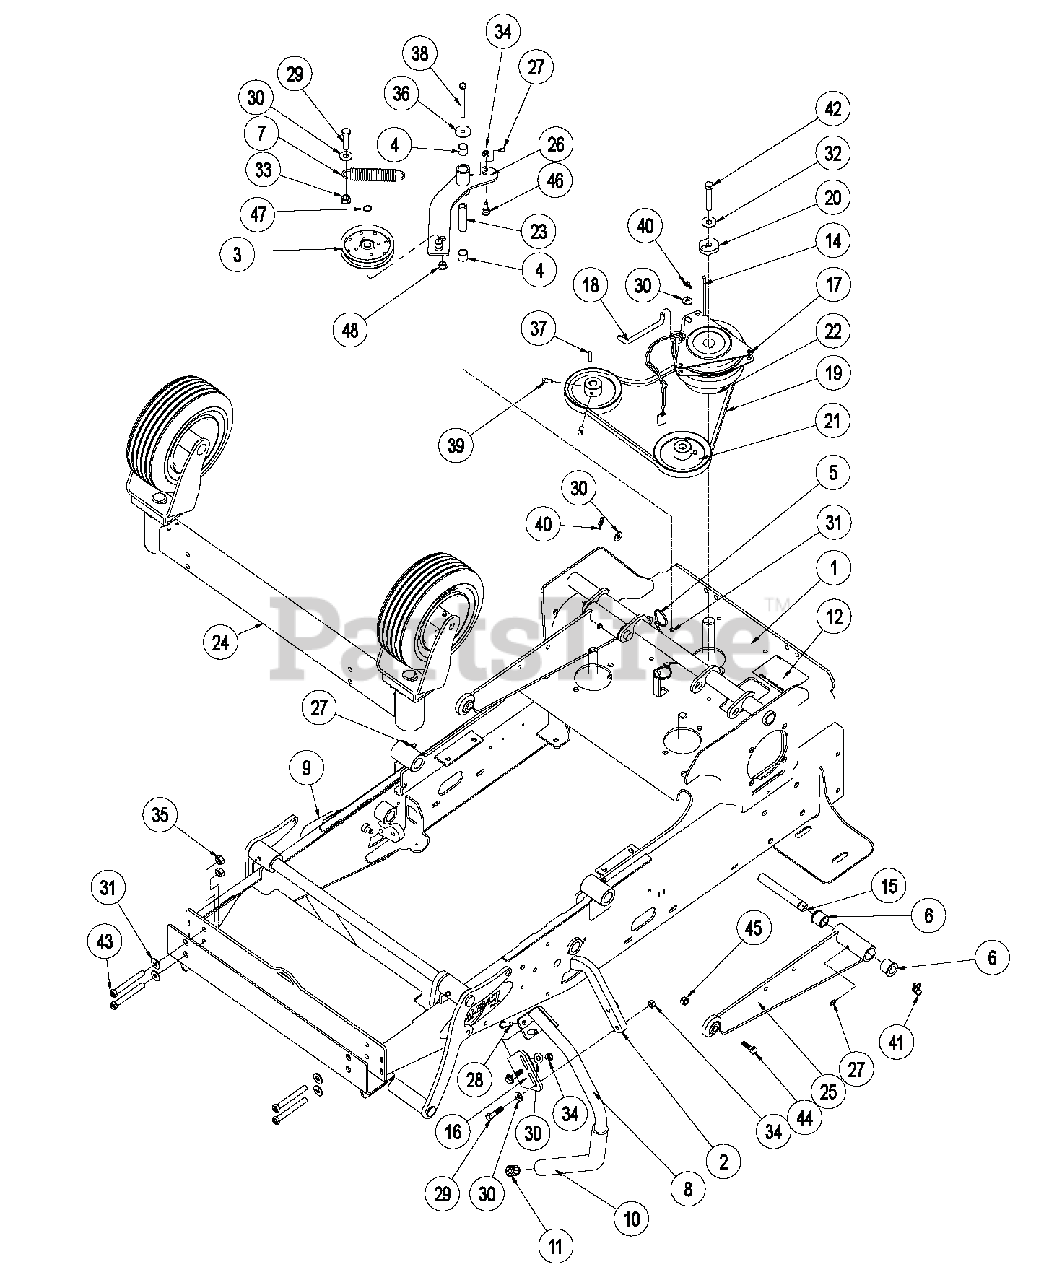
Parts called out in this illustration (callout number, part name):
1	ASSY, HORN FRM & LFT W/DCL S/O
2	PLATE, STEERING CONTROL
3	PULLEY, FLAT 4.50X.669 W/BRG
4	BRG, SLV .753X.878X.750
5	CABLE TIE, .15 X 8.50
6	BRG, FLG .750X1.13X1.00
7	SPRG, EXTENSION
8	WLDT, LH STEERING HANDLE
9	WLDT, RH STEERING HANDLE
10	FOAM GRIP
11	PLUG, 7/8" END
12	DECAL, PUMP BELTS
13	DECAL, 9" EVERRIDE LOGO SM
14	KEY, .250 X .250 X 4.62 SQ
14	KEY, .250 X .250 X 4.50 SQ
15	PIN, MFG .750X5.38X4.88 XDRL Y
16	PLATE, STEERING CONTROL BENT
17	CLUTCH, ELECT - OGURA GT, 2.5
18	ROD, CLUTCH ANTIROTATION
19	BELT, HA 48.2 EL AMD GP
20	WASHER, CLUTCH UNIVERSAL W/KEY
21	PULLEY, V-BELT 5.00X.591 W/KEY
22	PULLEY, V-BELT 4.50X1.00 W/KEY
23	TUBE, RD .750 X .156 X 3.05
24	ASSY, FRONT AXLE
25	WLDT, DECK PUSH LINK
26	WLDT, HORNET PUMP GEN I RETRO
27	FTG, 1/4-28 STRGT GREASE ZERK
28	BOLT, 3/8-16X1.25 HEX 5 Y
29	BOLT, 3/8-16X1.50 HEX 5 Y
30	WASHER, .313 REG FLAT Y
31	WASHER, .375 REG FLAT Y
32	WASHER, .438 REG FLAT
33	LOCKNUT, 3/8-16 WHIZ Y
34	LOCKNUT, 3/8-16 CROWN Y
35	LOCKNUT, 7/16-14 CROWN Y
36	WASHER, .375X1.50X.063 FLAT Y
37	KEY, M5 X M5 X M30 RD
38	BOLT, 3/8-16X4.00 HEX 5 Y
39	SET SCREW, 5/16-18X.625 SQ CUP
40	RING, RUE .375 X .054 X 1.254
41	RING, RUE .750 X .080 X 2.081
42	BOLT, 7/16-20X2.75 HEX 5 Y
42	BOLT, 7/16-20X2.25 HEX 5 Y
43	BOLT, 7/16-14X3.50 HEX 8 Y
44	BOLT, 1/2-13X2.25 HEX 5 Y
45	LOCKNUT, 1/2-13 CROWN
46	BOLT, 1/2X1.06X3/8-16 SLD 5 Y
47	SNAP RING
48	BRG, FLG .502X.629X.421
